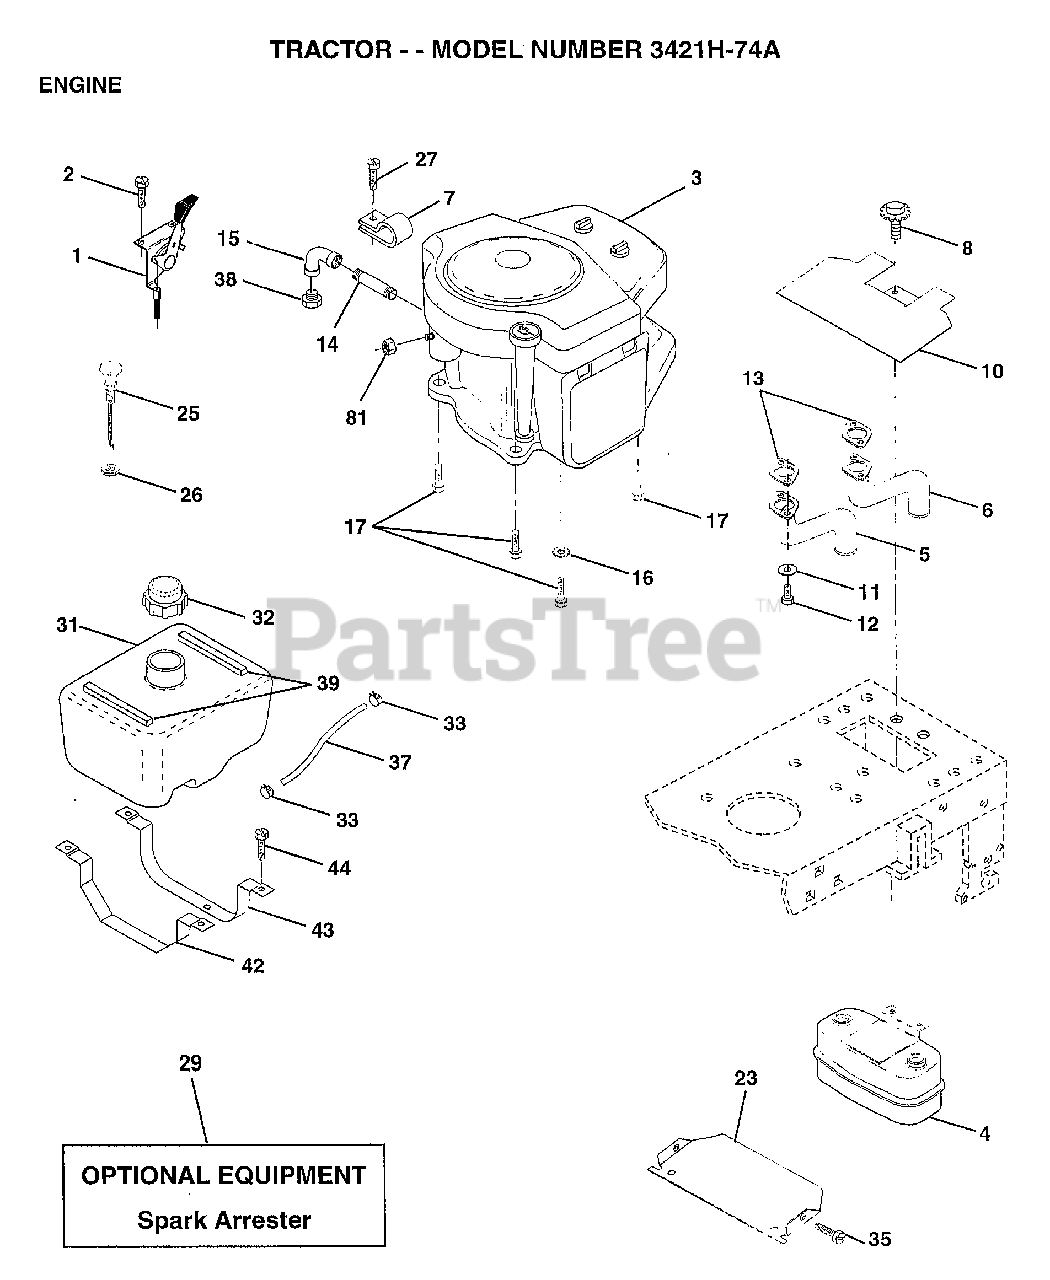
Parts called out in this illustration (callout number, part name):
2	SCREW LT
4	MUFFLER.TW.LOTONE
5	EXHAUST.B&S.18.LH
6	EXHAUST.B&S.18.RH
7	CLAMP.TUBE.DBL.EN
8	BOLT.5/16-18.UNC
10	SHIELD.HEAT.
14	PIPE NIPPLE LT
15	ELBOW
16	LOCKWASHER
17	SCREW LT
23	SHIELD-HEAT
25	"CONTROL.CHOKE.51"""
26	"NUT,KEPS 3/8-24IM"
27	"SCREW-TT,10-32 FL"
31	TANK FUEL 1.9 NAT
32	CAP ASM FUEL
33	HOSE CLAMP
35	SCREW
37	HOSE T
39	"STRIP,FORM"
42	STRAP TANK FUEL
43	STRAP TANK FRONT
44	SCREW
81	NUT
